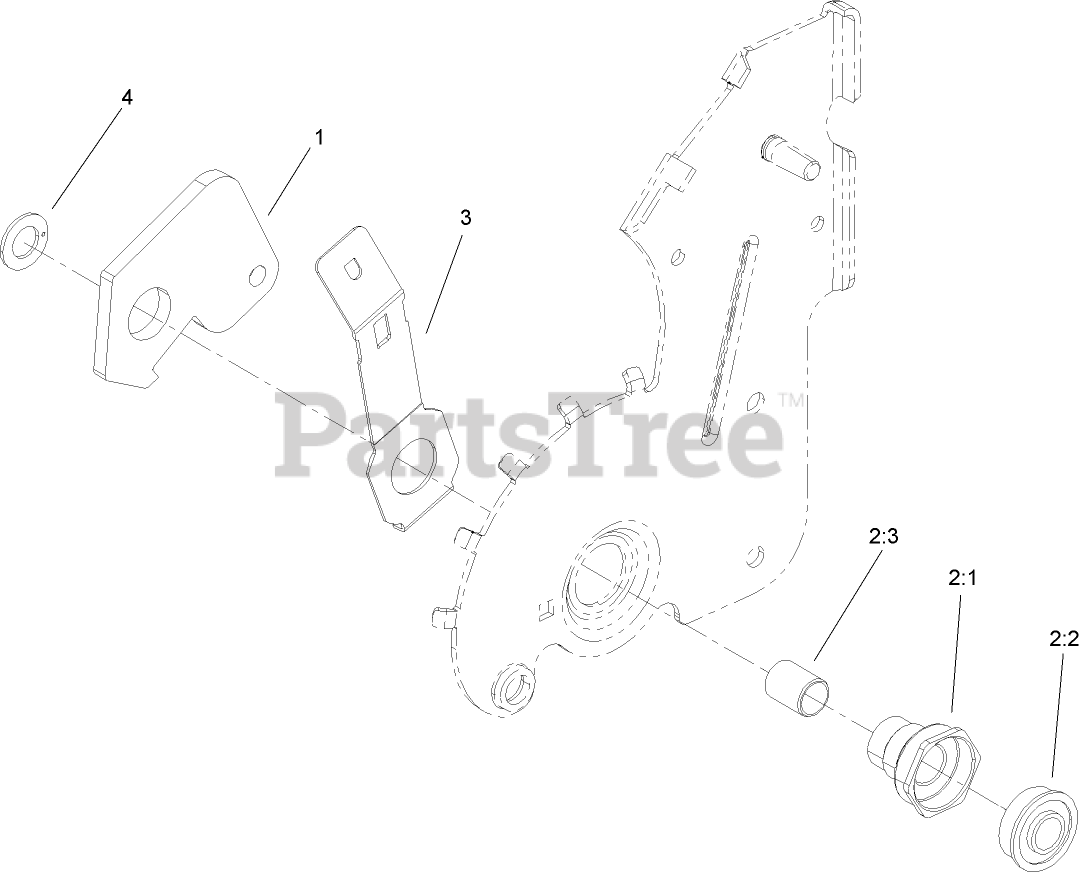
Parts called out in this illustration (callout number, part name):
1	ARM-PIVOT, REAR
2:1	RETAINER-BUSHING, HOC
2:2	BEARING-BALL
2:3	BUSHING-SLEEVE
3	ARM-SPRING
4	WASHER-THRUST
